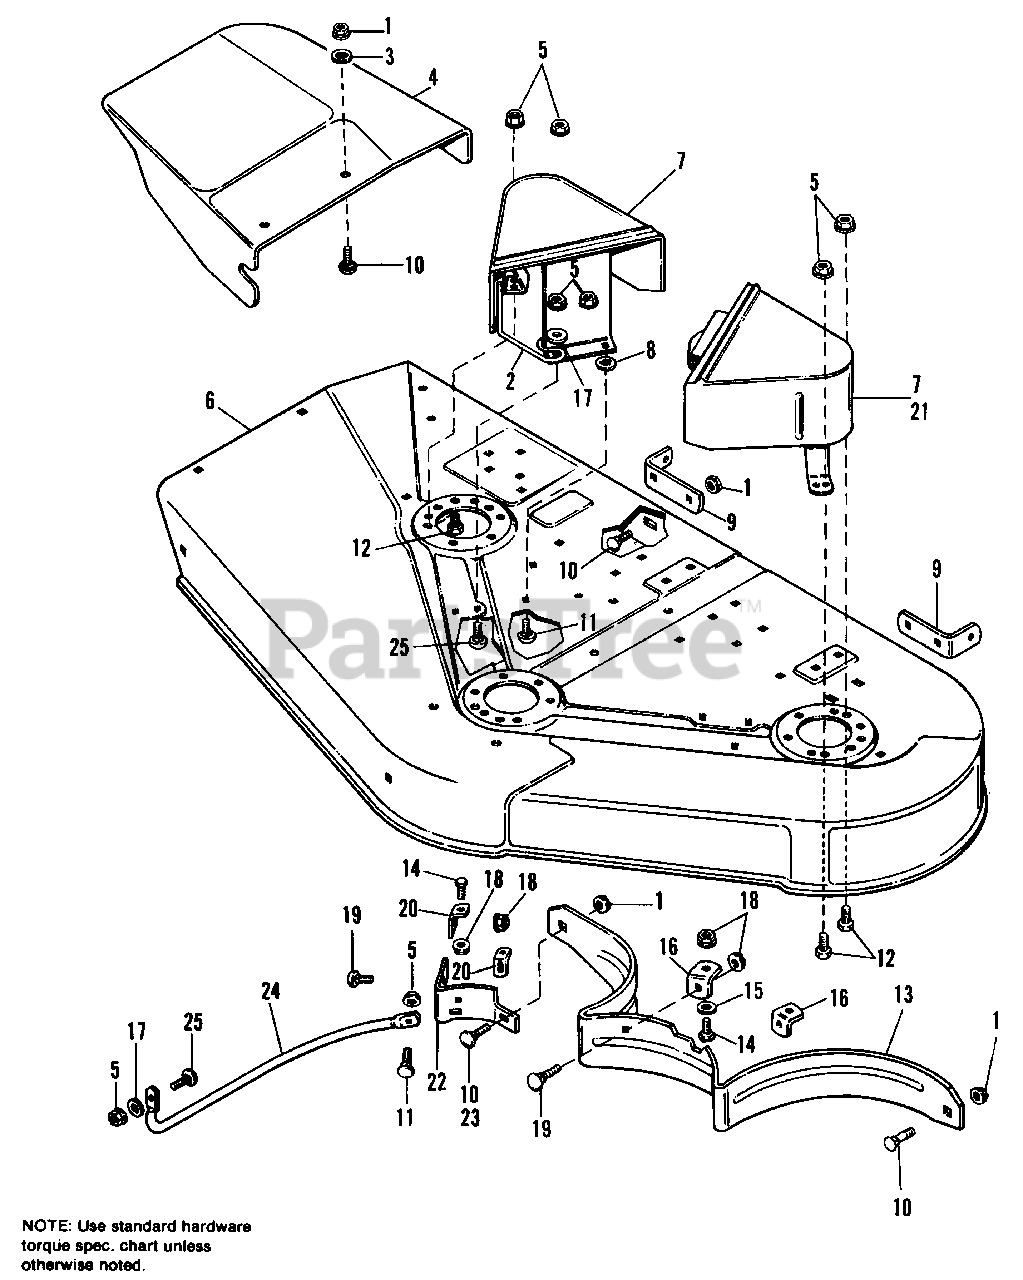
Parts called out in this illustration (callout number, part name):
1	NUT, Hex, Flange Whizlock 3/8-16 (Qty. 7 used on 48")
3	WASHER, Plain
5	NUT, Hex, Flange Whizlock, 5/16-18 (Qty. 8 used on 42")
6	42" ROTARY MOWER HOUSING
6	48" ROTARY MOWER HOUSING
7	ARBOR COVER ASSY.(Qty. 1 used on 42")
8	PUSHNUT, 5/16 (Qty. 2 used on 42")
9	BRACKET, Roller Support
10	BOLT, Carriage, 3/8-16 x 3/4 (Qty. 7 used on 48")
11	BOLT, Carriage, 5/16-18 x 3/4 (Qty. 2 used on 42")
12	CAPSCREW, Hex, 5/16-18 x 1
13	BAFFLE-42"
14	CAPSCREW, Hex, 1/4-20 x 3/4
15	WASHER, 1/4
16	CLIP, Baffle
17	WASHER, 11/32 x 1
18	NUT, Hex, Flange Whiz, 1/4-20
19	BOLT, Carriage, 1/4-20 x 5/8
20	CLIP GUARD 8 BAFFLE
21	ARBOR COVER ASSY. (42" only)
22	BAFFLE, Discharge
23	BOLT, Carriage, 3/8-16 x 1.00 (48" only)
24	GUARD, Mower Discharge
25	BOLT, Carriage, 5/16-18 x 1
